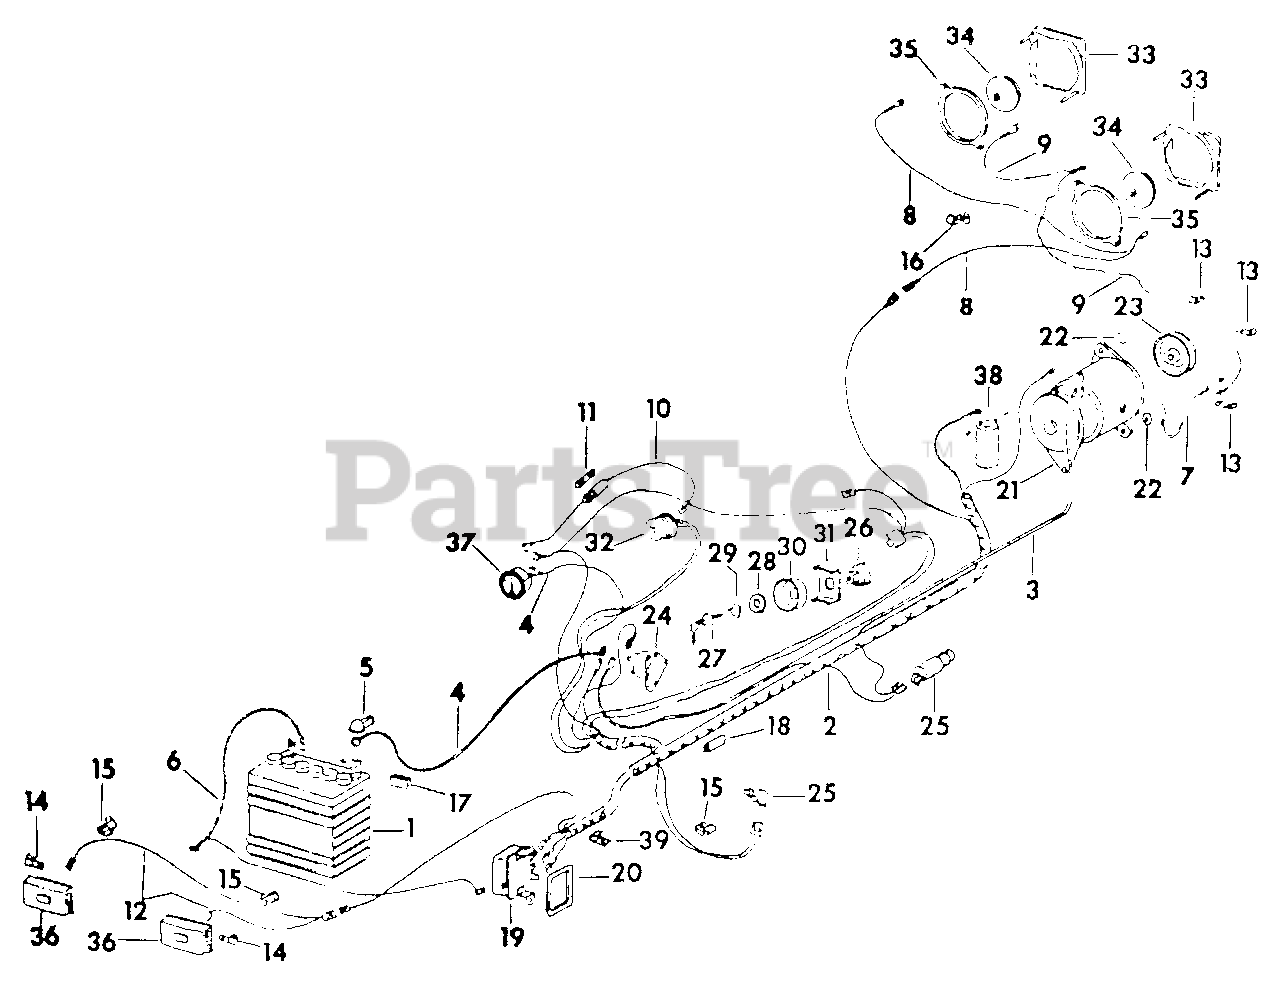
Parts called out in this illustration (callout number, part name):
1	Battery, IH Low Maintenance, 12 Volt
2	Cable Harness Rework Package
3	Cable, Magneto Switch to Generator A Terminal
4	Cable, Battery (Positive)
5	Cover, Battery Terminal
6	Cable, Battery Neg Terminal to Ground
7	Cable, Engine to Ground
8	Cable, Headlight
9	Cable, Headlight to Ground
10	Cable, Switch to Charge Indicator
11	Fuse, 10 Amp Slo-Blo
12	Cable, Taillight
13	Clip, Cable
14	Clip, Taillight
15	Clip, Safety Starting Switch Cable
17	Grommet, Seat Support Edge
18	Grommet, Frame Edge
19	Regulator, Voltage
20	Gasket, Voltage Regulator
21	Starter Generator Assy
22	Shim, Starter-Generator Mtg Bolt
23	Pulley, Starter-Generator Drive
24	Switch, Magnetic
25	Switch Assy, Neutral Starting
26	Switch w/Keys, Battery Ignition Key Start
27	Key, Ignition Switch
28	Washer, Battery Ignition Switch
29	Nut, Battery Ignition Switch
30	Socket, Ignition Switch
31	Retainer, Ignition Switch
32	Switch, Lighting
33	Rim, Headlight
34	Unit, Sealed Beam
35	Ring, Headlight Clamp
36	Taillight Assy
37	Indicator, Charge
38	Coil
39	Clip, Right Front Fender Mtg Screw Cable
